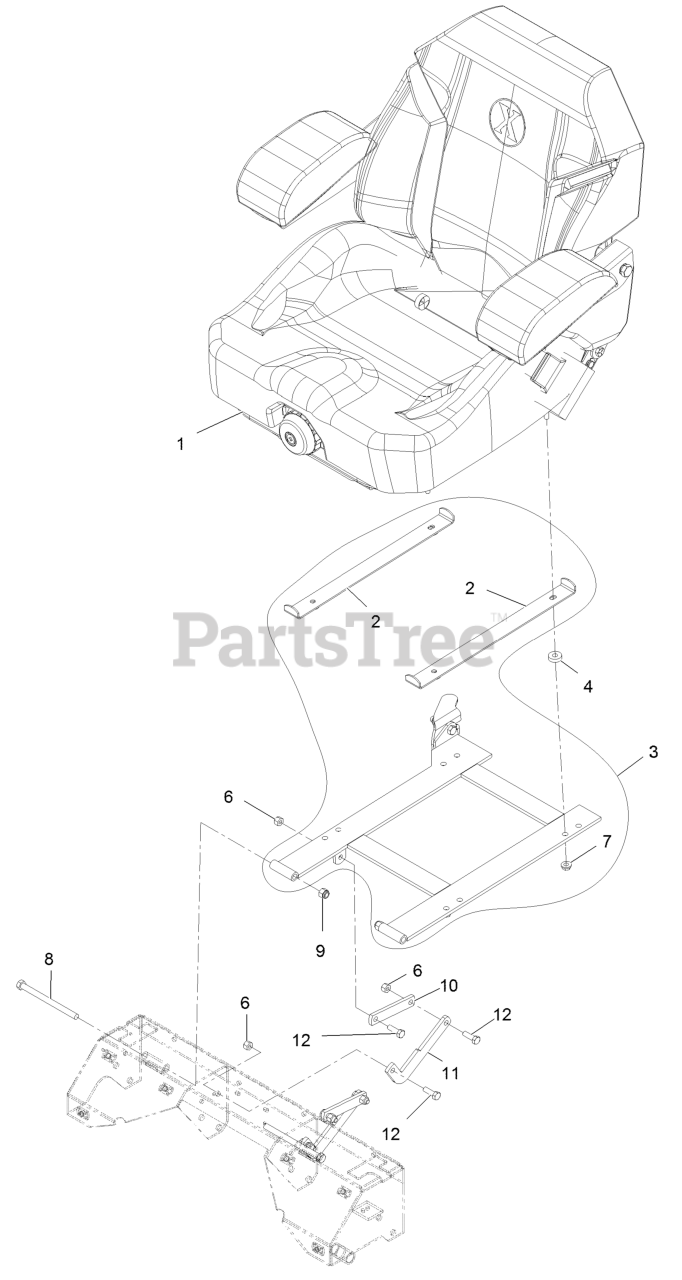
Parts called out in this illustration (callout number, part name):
1	KIT-SUSPENSION SEAT
2	STOP, SEAT
3	KIT,SEAT FRAME SERVICE
6	NUT-LOCK, NI
8	SCREW-HH
9	NUT-LOCK, NI
10	LINK-STOP, SEAT
11	LINK-STOP, SEAT
12	SCREW-HH
